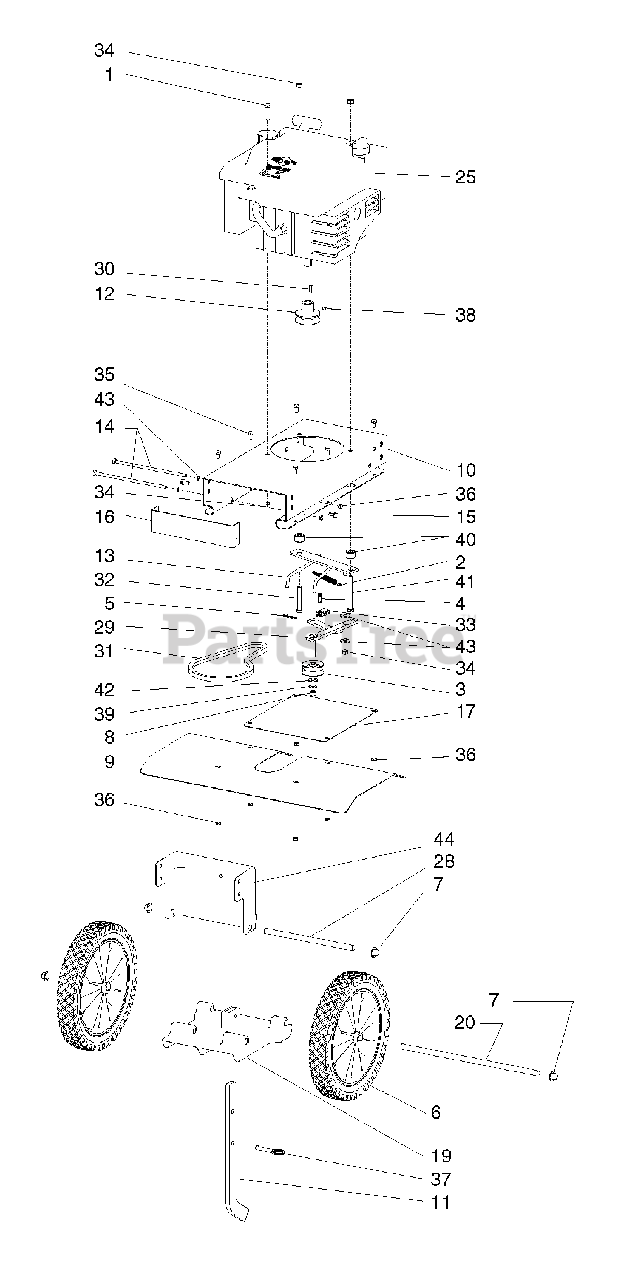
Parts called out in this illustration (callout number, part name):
1	BOLT, Hex-Head Capscrew, 5/16-18 x 1-1/4
2	SPRING, Forward Arm
3	PULLEY, Reverse Idler
4	PIN, Link
5	PIN, Cotter
6	WHEEL & TIRE ASSEMBLY
7	NUT, Push, 1/2 Dia.
8	NUT, Hex, Non-Locking, 3/8-16
9	SHIELD, Tine
10	FRAME, Engine Mount
11	LEVER, Depth Regulator
12	PULLEY, Engine, Single-Groove, 3/4 I.D.
13	BELT GUIDE & MOUNT
14	BOLT, Hex-Head Capscrew, 1/4-20 x 7-1/2
15	SCREW, Sheet Metal, 1/4 x 3/4
16	COVER, Front Belt
17	SHIELD, Dirt
19	TAIL MOUNT, Lower
20	SHAFT, Wheel, 1/2
25	* ENGINE, 6.50 T.R. Briggs & Stratton
28	SHAFT, Tail Mount Hinge, 1/2
29	IDLER ARM, Forward
30	KEY, Square, 3/16 x 5/8
31	BELT, Forward
32	BOLT, Hex-Head, Capscrew, 5/16-18 x 2-1/4, G5
33	YOKE, Clevis, Zinc-Plated
34	NUT, Bi-Way Lock, 5/16-18
35	BOLT, Hex-Head, Capscrew, 1/4-20 x 2, G5
36	NUT, Hex Ny-Lock, 1/4-20
37	PIN, Detent, 5/16 x 2
38	SET SCREW, 1/4-20 x 1/4
39	WASHER, Spring-Lock, 3/8
40	SPACER, Guide Belt
41	BOLT, Hex-Head, 5/16-18 x 3-1/4
42	WASHER, Flat, 5/16
43	WASHER, Spring Lock, 1/4
44	TAIL MOUNT, Upper
